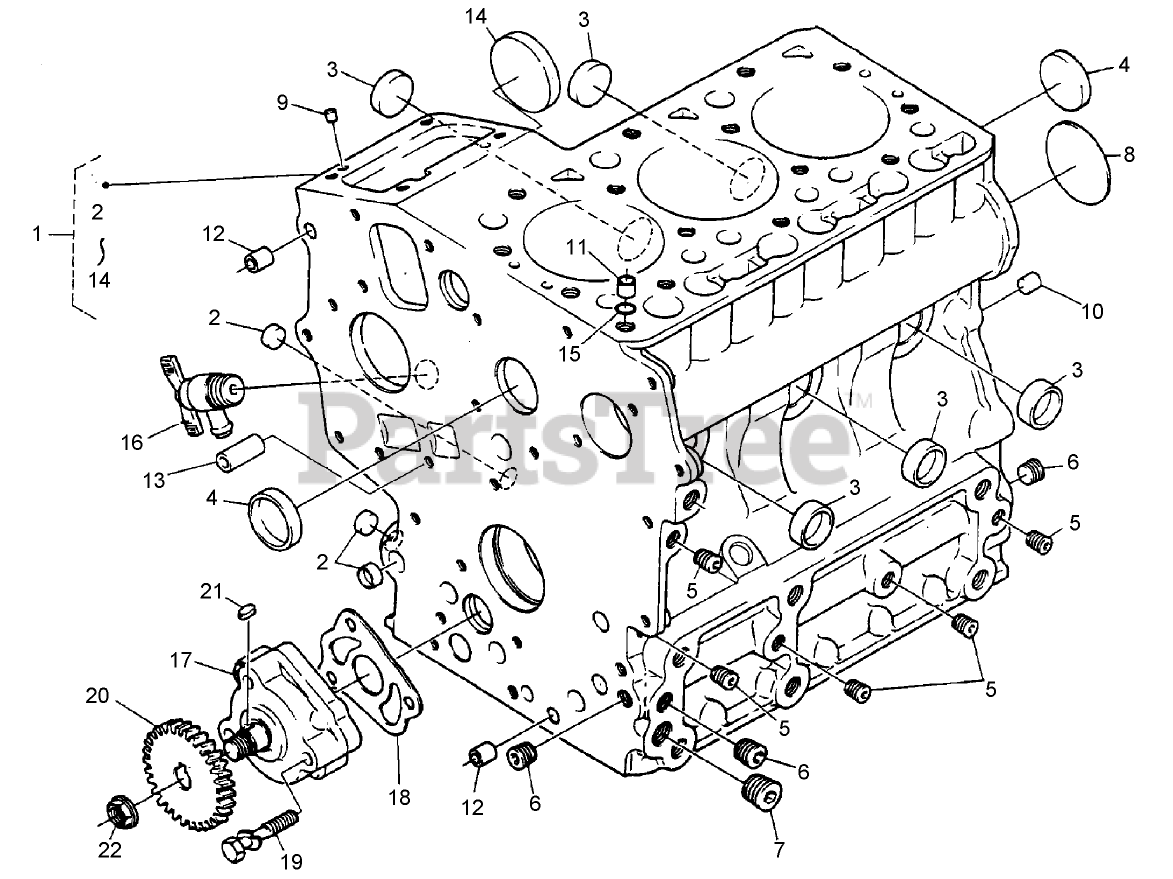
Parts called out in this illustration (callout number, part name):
1	CRANKCASE ASM
2	CAP-SEALING
3	CAP-SEALING
4	CAP-SEALING
5	PLUG
8	PLUG-EXPANSION
9	PIN-STRAIGHT
10	PIN-STRAIGHT
11	PIN-PIPE
12	PIN-PIPE
13	PIN-PIPE
14	COVER-FUEL, CAMSHAFT
15	O-RING
16	DRAIN COCK ASM
17	OIL PUMP ASM
18	GASKET-PUMP, OIL
20	GEAR-DRIVE, OIL PUMP
21	KEY-FEATHER
22	NUT-FLANGE
